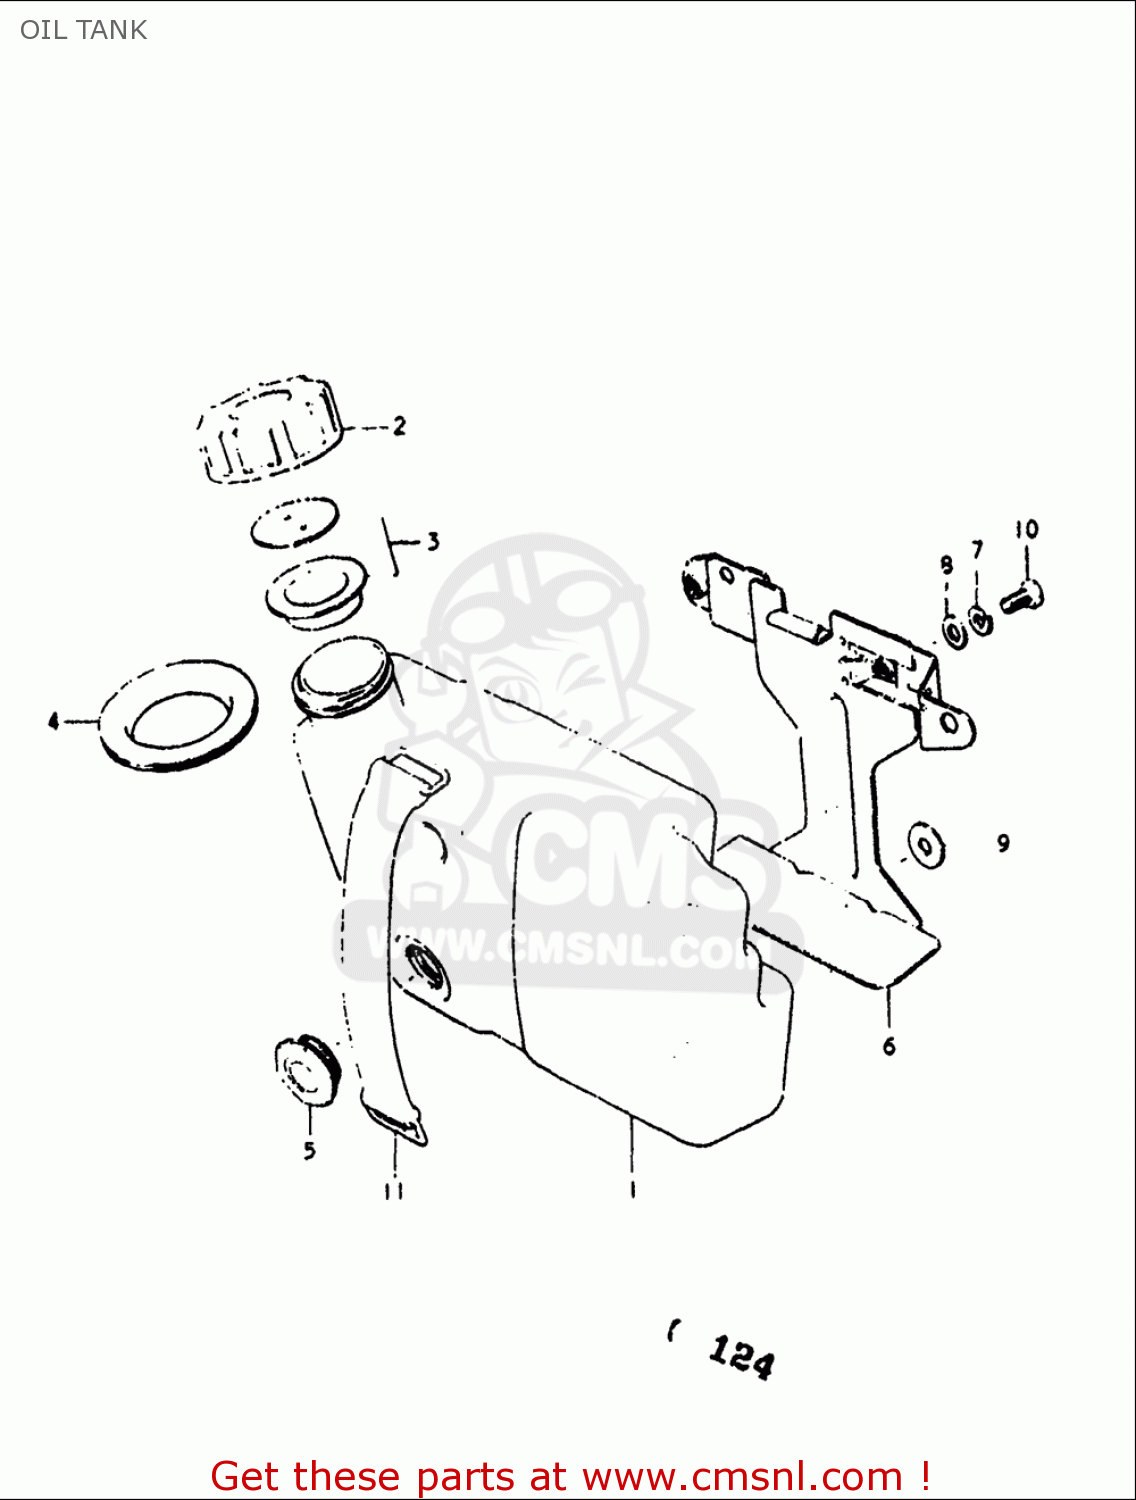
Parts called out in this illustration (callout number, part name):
2	CAP,OIL TANK
3	GASKET,OIL TANK CAP (NAS)
4	RUBBER,FUEL TANK INLET
5	LENS SET,OIL LEVEL
7	WASHER,LOCK
8	WASHER
9	WASHER(6.5X18X1.6)
10	SCREW(6X12)
11	BAND
